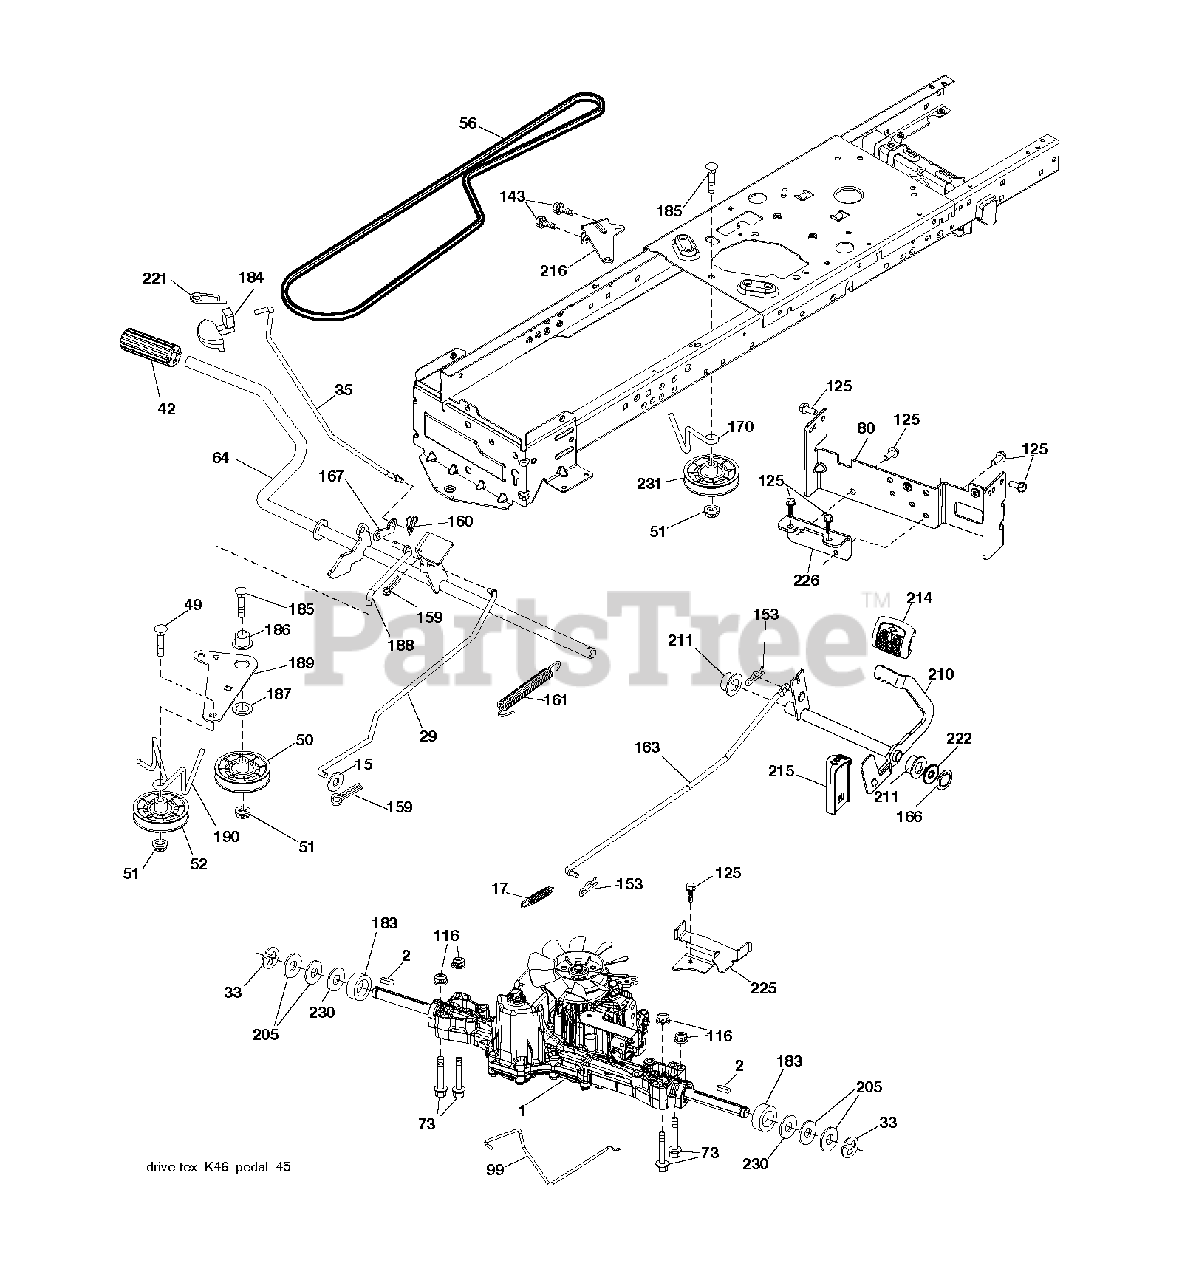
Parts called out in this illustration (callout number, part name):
2	SQUARE KEY
17	SPRING.BRAKE.K46.GREEN
29	ROD.BRAKE.K46
33	E-RING LT
35	ROD, BRAKE, PARK
42	PEDAL COVER T
49	BOLT
50	IDLER.FLAT.910.OFFSET
51	NUT LOCK FLG 3/8-16 UNC
52	IDLER.V-GROOVE.910.OFFSET
64	SHAFT.ASM.PEDAL.BRK.CNTR
73	BOLT HEX 5/16-18 GR 5
80	STRAP TORQUE
99	ROD.SPRING.BYPASS.K46.LT.Z
116	NUT LOCK HEX FLANGE 5/16-18
125	SCREW
153	RETAINER M
159	COTTER PIN
160	RETAINER CLIP
161	SPRING, RETURN LT
163	ROD.CONTROL.PEDAL.K46
166	NUT.PUSH.625.2006
167	LATCH.BRAKE.SPRING
170	KEEPER.CENTER SPAN.1.688
183	SPACER AXLE
184	HANDLE PARKING BRAKE
186	SPACER.RETAINER
187	WASHER 12/32X2X10GA
188	LINK.CLUTCH.GROUND.DRIVE
189	BELLCRANK.GROUND.DRIVE.TEX.
190	KEEPER.BELLCRANK.DRIVE
210	ROCKER.ASM.PEDAL.CONTR
211	BEARING.NYLON
214	PAD PEDAL FORWARD
215	PEDAL.REVERSE.TEX.GT.4
216	BRACKET.PULLEY.IDLER.W/TEX
221	RETAINER.SPRING.CLIP.H
222	WASHER 21/32 X 1-1/4 X 10 GA.
225	KEEPER.BELT.TRANSAXLE.K46
226	BRACKET.MOUNT.TORQUE.K46.TLT
230	WASHER.HARDENED
231	IDLER.V-GROOVE.1.688.OFFSET
